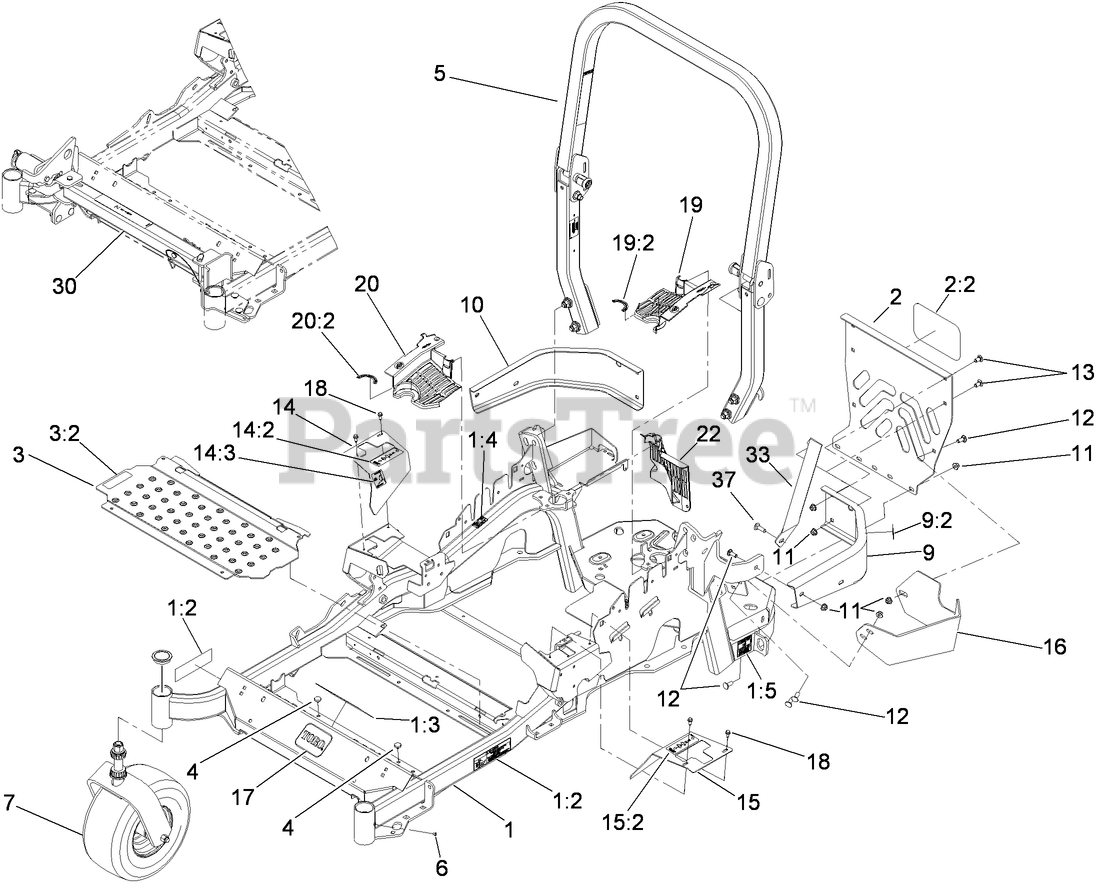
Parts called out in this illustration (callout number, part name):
1	MAIN FRAME ASM
1:2	DECAL-WARNING, SPRING LOAD
1:3	DECAL-DANGER SLOPE W/ROPS
1:4	DECAL-WARNING
1:5	DECAL-HAZARD, PINCHED FINGER
2	REAR GUARD ASM
2:2	DECAL
3	FLOORPAN ASM
3:2	DECAL-MISSING, COVER
4	BUMPER
5	ROPS ASM
7	Caster Wheel ASM
9	LH REAR BUMPER ASM
9:2	DECAL-WARNING
10	BUMPER-RH
11	NUT-HF, NI
12	SCREW-CARR
13	SCREW-CARR
14	RH MOTION CONTROL COVER ASM
14:2	DECAL-CONTROL, MOTION
14:3	DECAL-PARKING BRAKE
15	LH MOTION CONTROL COVER ASM
15:2	DECAL-CONTROL, MOTION
16	GUARD-MUFFLER
17	DECAL
18	SCREW-HWH
19	LH HYDRO GUARD ASM
19:2	DECAL-HYDRO OIL
20	RH HYDRO GUARD ASM
20:2	DECAL-HYDRO OIL
22	GUARD-HYDRO, REAR (RH)
30	G3 Z STAND ASM
37	BOLT-CARR
